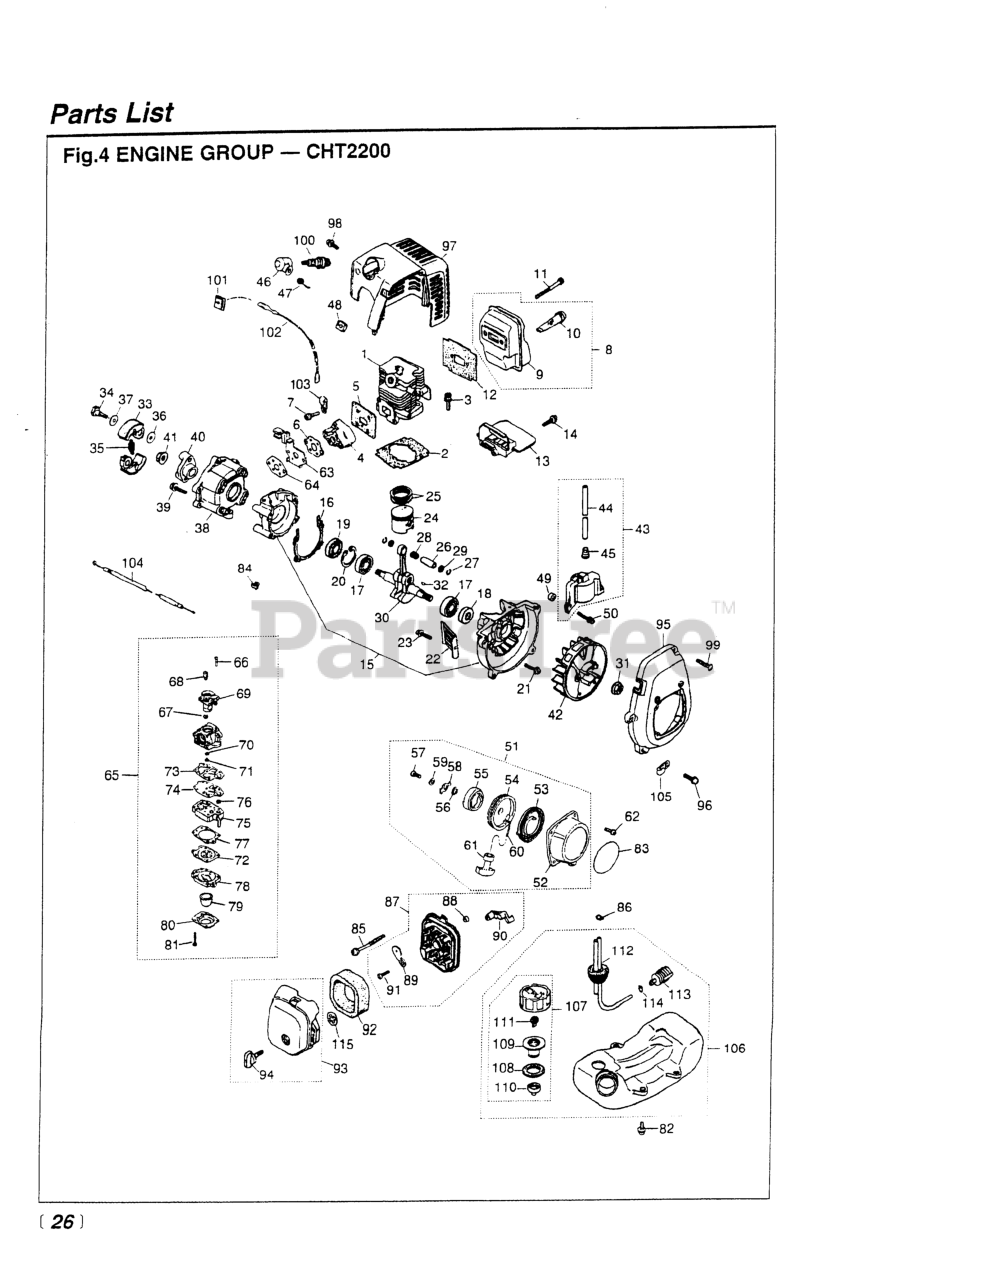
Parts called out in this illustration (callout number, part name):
1	CYLINDER
3	BOLT, M5 X 22
5	GASKET (RPLS -13120)
6	GASKET (REPLACES -13130)
7	SCREW, M5X20 (RPLS.1400-75510)
8	MUFFLER ASSEMBLY
10	ARRESTER (RPLS 5850-15140)
11	BOLT, M5 x 50
12	GASKET, MUFFLER
14	SCREW, M4 X 16
15	CRANKCASE COMP.
16	GASKET (RPLS -21140)
17	BEARING
18	SEAL, OIL (RPLS 1100-21210)
19	SEAL, OIL (RPLS 1140-21220)
20	RING, SNAP, M28 x 1.2
21	BOLT, M5 X 30
23	SCREW,M5 X 14 (RPLS 1400-15510
24	PISTON (REPLACES 1140-41110)
25	RING, PISTON (RPLS 1850-41210)
26	PIN, PISTON 5x8x26
27	RING, SNAP (RPLS 1101-41320)
29	WASHER
30	CRANKSHAFT (RPLS -42000)
32	KEY
33	SHOE (RPLS 1100-51114)
34	BOLT
35	SPRING, CLUTCH (RPLS-51220)
36	WASHER, FLAT (USE 182303)
38	CASE, CLUTCH
39	SCREW
40	PLATE, CLUTCH
43	COIL ASSY (RPLS 5500-71200)
44	CORD
45	CAP
47	SPRING
48	GROMMET
49	SPACER (RPLS -71260)
50	BOLT
52	CASE, RECOIL
53	SPRING, SPIRAL
56	WASHER
57	SCREW
58	RETAINER (RPLS 1861-75161)
59	WASHER
60	ROPE
62	SCREW, M4 x 12
63	BRACKET
64	GASKET (REPLACES -13130)
65	CARBURETOR
67	RING
68	SWIVEL
69	VALVE ASSY
70	RING, O
72	DIAPHRAGM (USE 4810-81260)
73	GASKET, PUMP
74	DIAPHRAGM
75	BODY, PUMP
77	GASKET, DIAPHRAGM
78	BODY, PURGE
79	PUMP, PRIMING
80	COVER, PUMP
81	SCREW
82	SCREW
84	CAP, CABLE END
85	SCREW, M5 x 60
86	CLIP
87	BODY-A (RPLS -82101)
88	SLEEVE
89	PLATE, CHOKE (RPLS-82130)
90	LEVER, CHOKE
91	SCREW (REPLACES 50030272)
92	ELEMENT
94	KNOB (RPLS -82220)
95	COVER, FAN
96	SCREW, M5X20 (RPLS.1400-75510)
97	COVER, ENGINE(USE-32101)
98	SCREW, M5 x 12
99	SCREW, HOUSING
102	CORD
103	CLAMP
104	CABLE
105	CLAMP
108	PACKING
110	HOLDER, CAP
111	VALVE (NLA WHEN OUT)
112	PIPE COMPLETE
113	FILTER (RPLS 1850-85300)
114	CLIP (REPLACES 2841-31280)
115	RING
